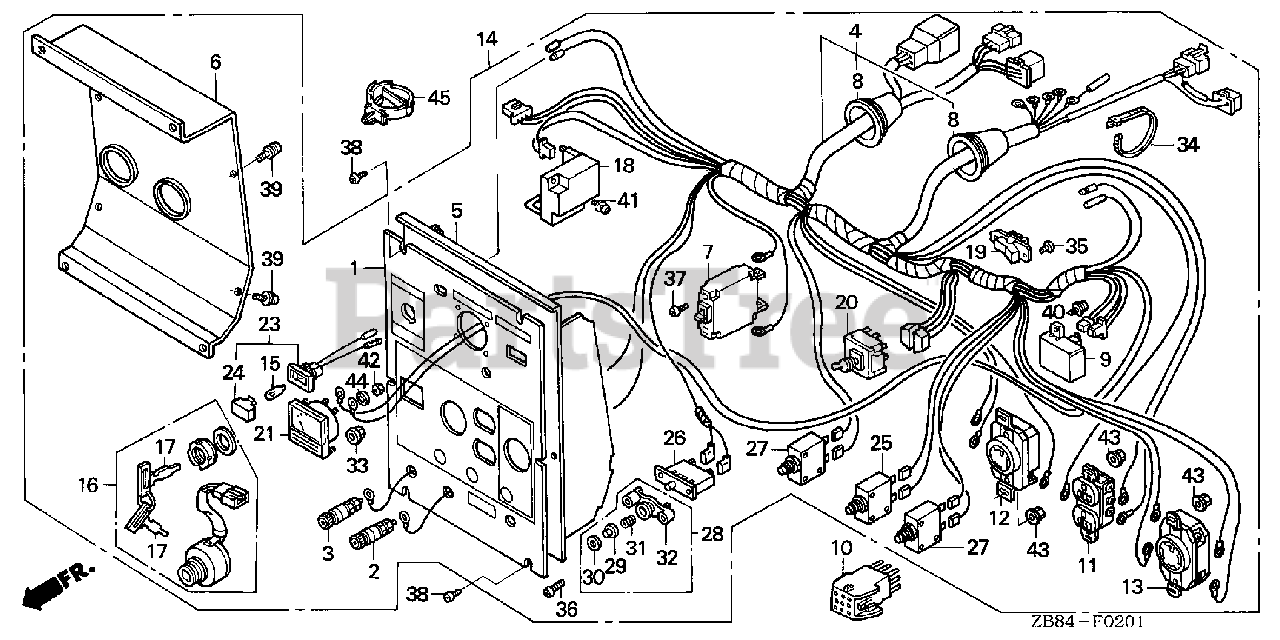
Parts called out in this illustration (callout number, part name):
1	MARK, CONTROL INDICATION
2	TERMINAL, D.C. OUTPUT (+)
2	TERMINAL, D.C. OUT (+)
3	TERMINAL, D.C. OUTPUT (-)
3	TERMINAL, D.C. OUT (-)
4	HARNESS ASSY., CONTROL (EXS-A)
5	PANEL, CONTROL
6	COVER, CONTROL
7	BREAKER, CIRCUIT (18A)
8	GROMMET, MAIN WIRE
9	DIODE ASSY.
10	CONNECTOR ASSY.
11	RECEPTACLE (20A/125V)
12	RECEPTACLE (30A/125V)
13	RECEPTACLE (30A/125-250V)
14	PANEL ASSY., CONTROL
15	BULB, WEDGE BASE (12V/2W)
16	SWITCH ASSY., COMBINATION
17	KEY
18	THROTTLE UNIT ASSY., AUTO
19	SWITCH ASSY., AUTO THROTTLE
20	SWITCH ASSY., VOLT CHANGE
21	METER ASSY., VOLT (300V)
23	SOCKET ASSY., LAMP (GREEN)
24	LENS (GREEN)
25	PROTECTOR, CIRCUIT (20A)
26	PROTECTOR, CIRCUIT (DC)
27	PROTECTOR, CIRCUIT (30A)
28	LENS ASSY., PROTECTOR
31	SPRING, COIL
32	HOLDER, LENS
33	NUT, FLANGE (3MM)
34	TIE, CABLE
35	SCREW, PAN (3X6)
36	SCREW, PAN (3X12)
37	SCREW, PAN (4X6)
38	SCREW, PAN (5X10)
39	SCREW-WASHER (4X8)
40	SCREW-WASHER (4X12)
41	SCREW-WASHER (5X12)
42	NUT, HEX. (3MM)
43	NUT, FLANGE (4MM)
45	STRAP, WIRE HARNESS (25MM) (BLACK)
